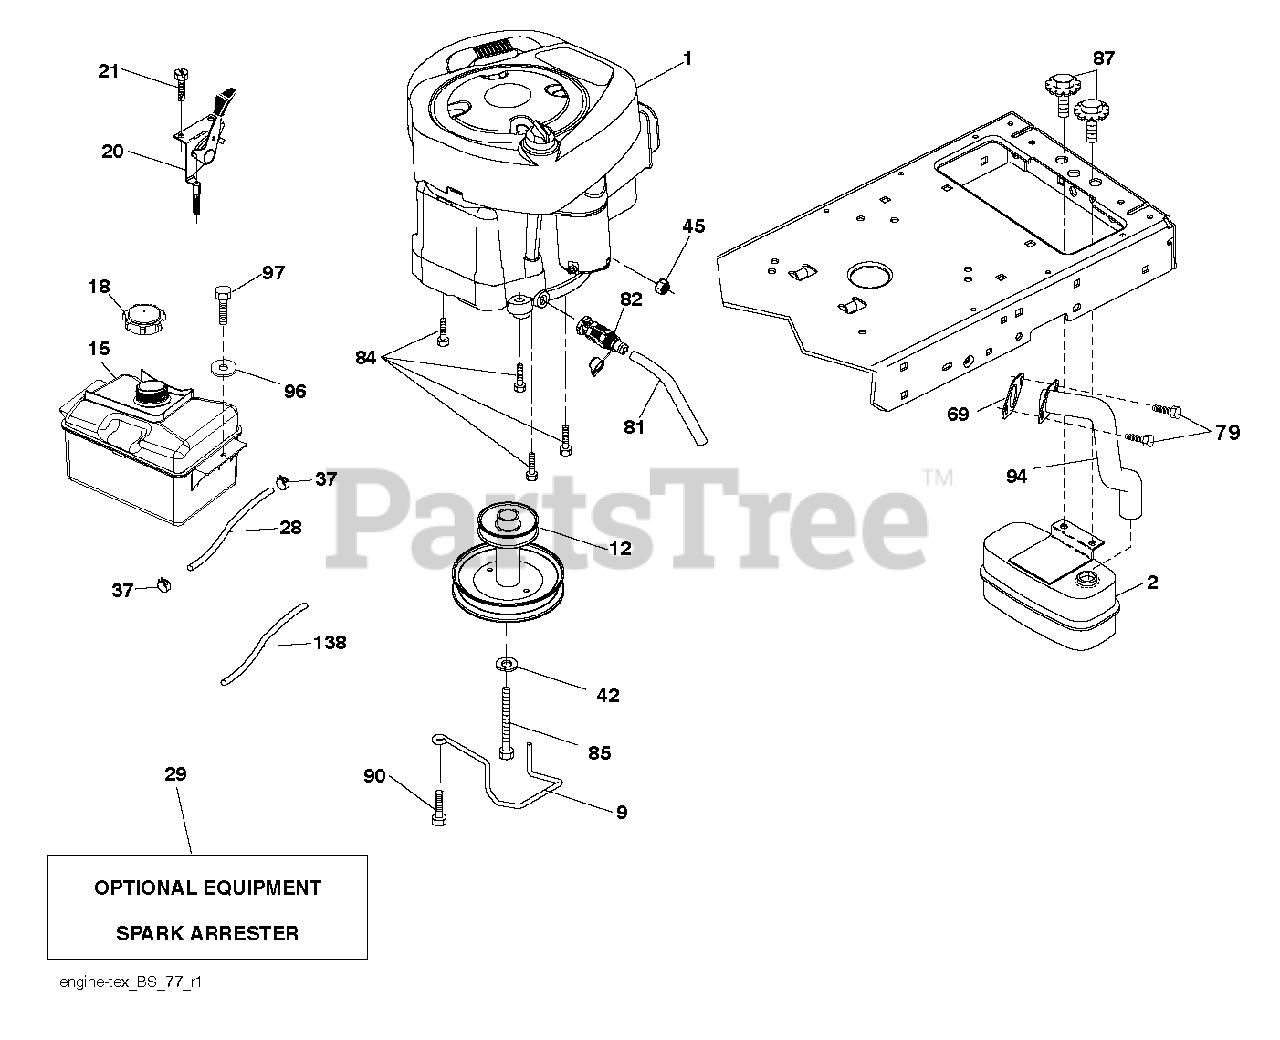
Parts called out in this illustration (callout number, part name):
2	MUFFLER.SINGLE.LRG.BRIGGS.KOHL
9	KEEPER.BELT.ENGINE
12	Engine Pulley
15	TANK.ASM.1.5GAL.FRT.W/CAP.EPA
18	CAP.FUEL.2 WAY VENT
28	LINE.FUEL.20"FRONT.EMI
29	KIT.SPARK ARRESTOR(392390 B&S)
37	HOSE CLAMP
42	LOCKWASHER
45	NUT
79	SCREW.SOCKET HD.5/16-1
81	TUBE, DRAIN OIL ASM.
82	VALUE.OIL.DRAIN
84	SCREW.3/8-16
85	BOLT HEX 7/16-20X4-1/4"
87	BOLT, 5/16-18 X 1 3/4
90	SCREW 3/8-16X1
94	Exhaust Tube, B&S 28/31
96	WASHER
97	SCREW HEXWSHR 1/4-20X3/4
138	RP PURGE LINE
